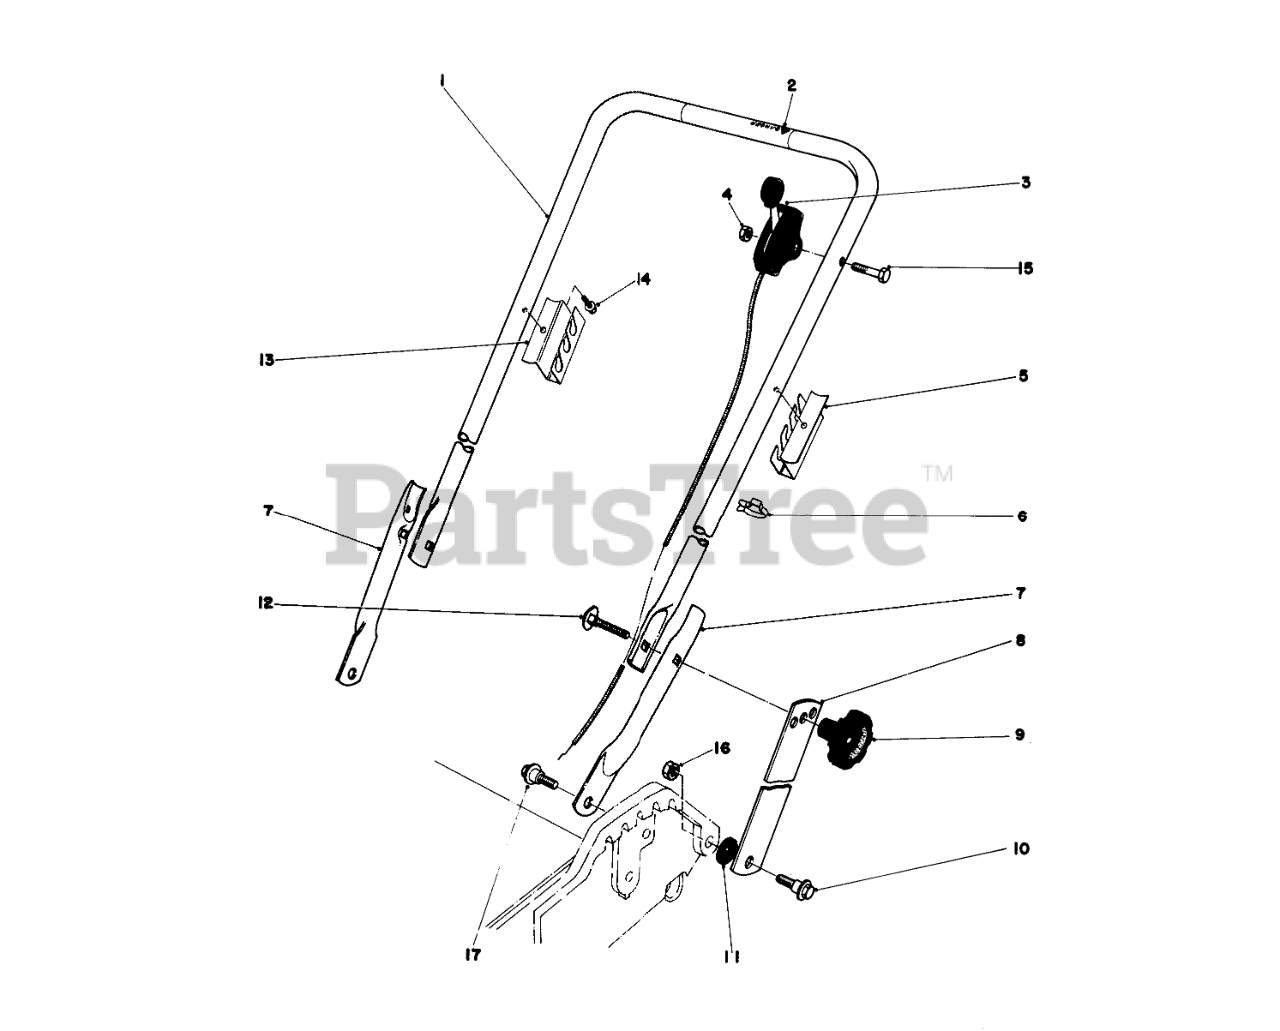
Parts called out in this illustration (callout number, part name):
1	Handle-Upper
2	Decal
3	Throttle Control
4	NUT-LOCK
5	SUPPORT BAG LH
6	BOWDEN CLIP
7	Hand-Lower
8	18" HANDLE LATCH
10	SCREW-SHOULDER
11	SPACER
12	SCREW-HANDLE
13	SUPPORT BAG RH
14	SCREW-HWHTF
15	SCREW-HH
16	Nut
17	SCREW-SHOULDER
